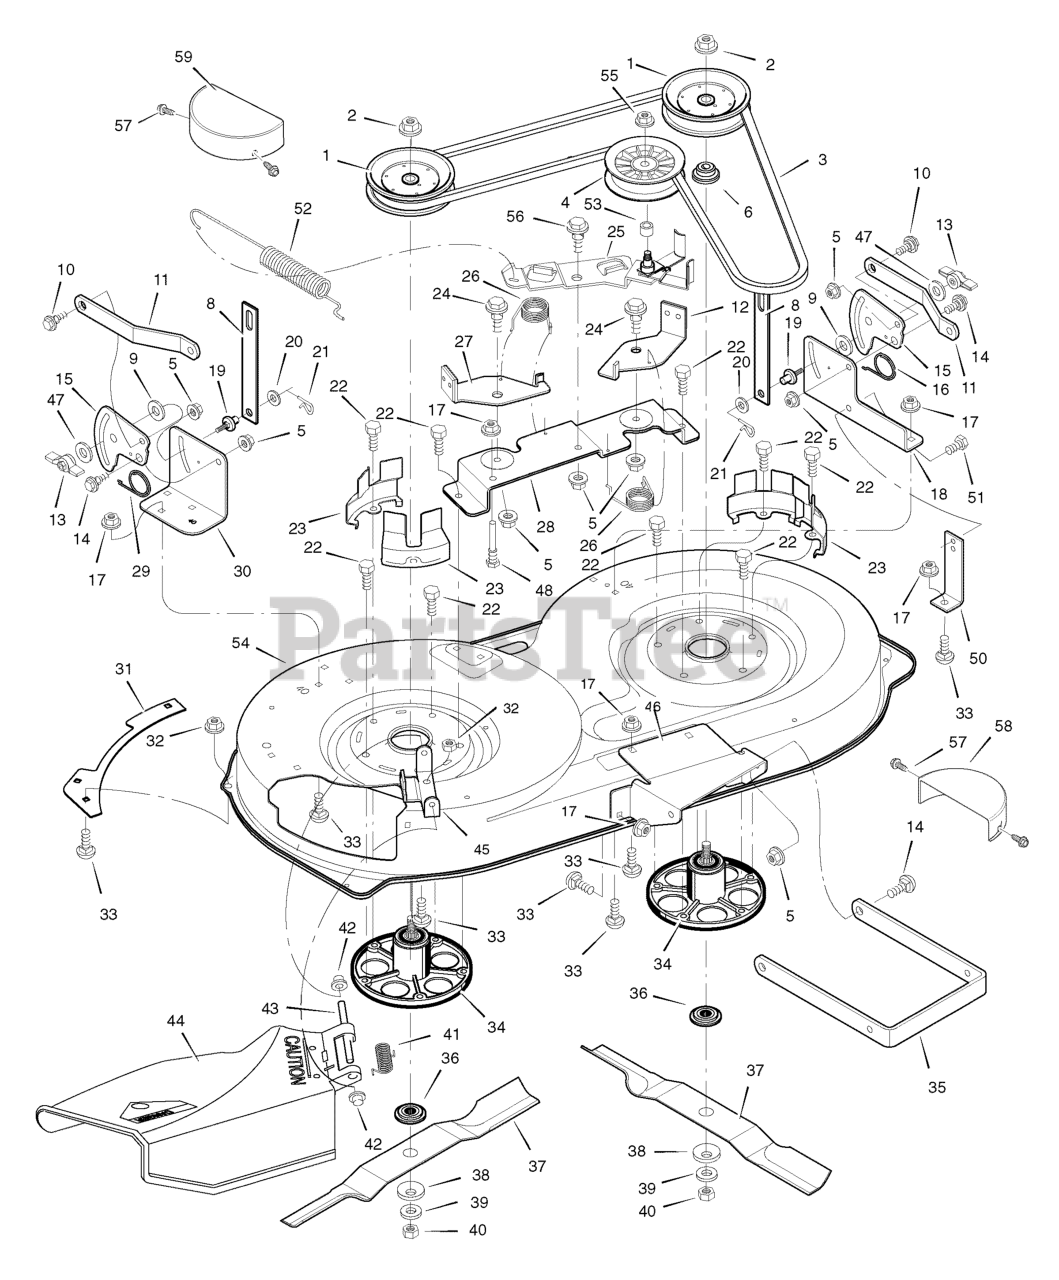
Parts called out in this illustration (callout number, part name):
1	Pulley, Jackshaft
2	Nut, Hex
3	Belt, Mower Drive
4	Pulley, Idler
5	Nut, Flange
6	Spacer, Pulley
8	Link, Lift
9	Pad, Friction
10	Bolt, Shoulder
11	Bracket, Suspension
12	Pad Assembly, Left Brake
13	Knob
14	Bolt, Shoulder
15	Plate, Suspension
17	Nut, Flange
18	Bracket, Suspension
19	Pin, Hanger
21	Pin, Cotter
22	Bolt
23	Cover, Pulley
24	Bolt, Shoulder
25	Arm, Idler
27	Pad Assembly, Right Brake
28	Bracket Assembly, Brake
30	Bracket, Suspension
32	Nut, Flange
33	Bolt, Carriage
34	Mandrell
35	Bracket, Suspension
36	Adapter, Blade
42	Cap, Push On
43	ROD, Deflector
44	Deflector Assembly
45	Bracket, Deflector
46	Bracket, Front Hanger
48	Guide, Belt
50	Bracket, Support
52	Spring, Extension
54	Housing, Blade
55	Nut, Flange
56	Bolt, Shoulder
58	COVER, Pulley L.H.
59	GUARD, Belt R.H.
